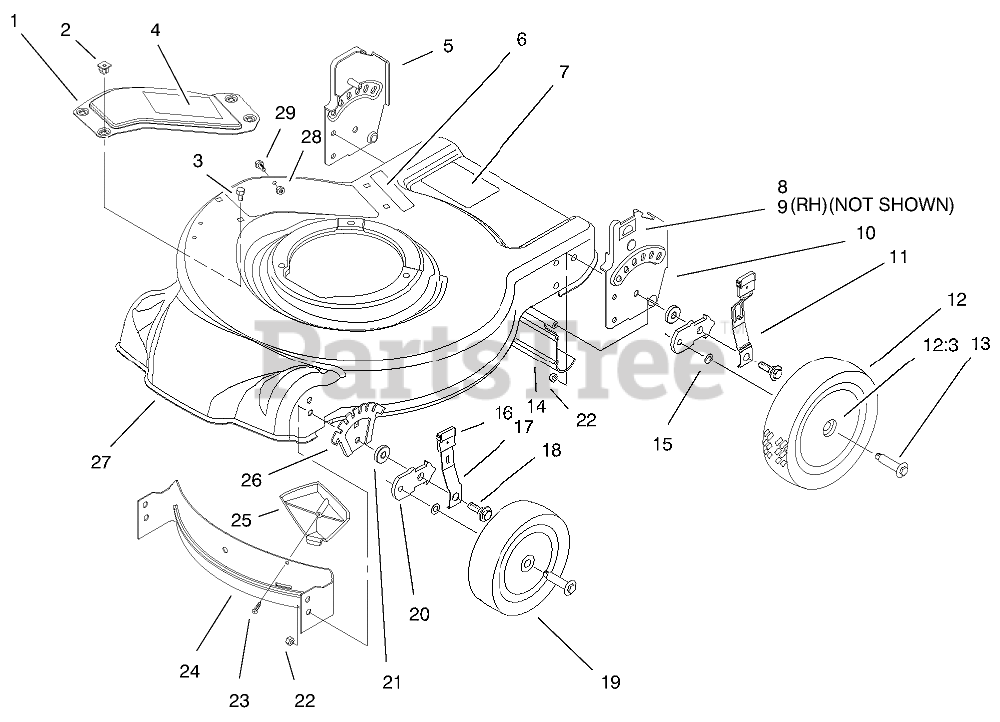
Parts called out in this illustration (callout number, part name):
1	COVER W/DECAL
2	NUT - CLIP
3	SCREW-HWH
4	DECAL - COVER
5	ASM - RH HANDLE BRACKET
6	DECAL - WARNING
7	DECAL-WARNING
8	DECAL-HOC, RH
9	DECAL-HOC, LH
10	ASM - LH HANDLE BRACKET
11	REAR SPRING ARM ASM
12	WHEEL ASM
12:3	BUSHING
13	BOLT-SHOULDER
14	SHIELD-TRAILING
15	WASHER
16	KNOB-LEVER, HEIGHT ADJUSTMENT
17	ARM-FRONT SPRING
18	BOLT-SHOULDER
19	WHEEL ASM 7" GRAY
20	Bracket-Wheel Height Adj
21	WASHER
22	NUT-LOCK, NI
23	SCREW-PPH
24	Baffle Front
25	KICKER-FRONT
26	Plate H.O.C.
27	HOUSING W/DECALS
28	NUT-LOCK, NI
